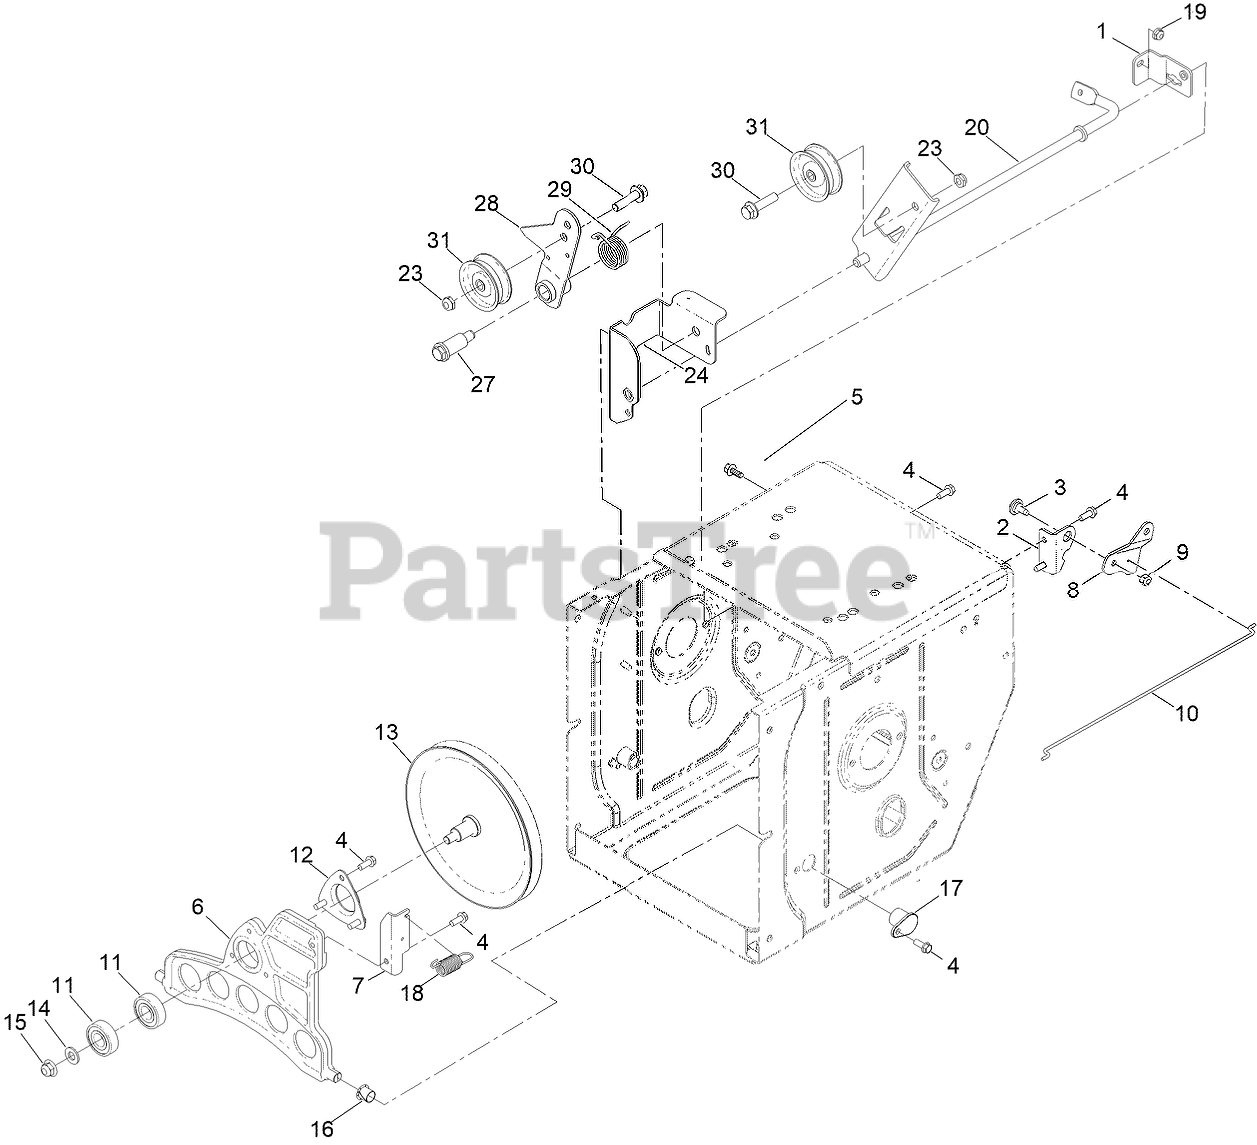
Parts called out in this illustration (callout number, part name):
1	BRACKET-CLUTCH, IMPELLER
2	BRACKET- BELLCRANK
3	SCREW-SHOULDER
4	SCREW-HWH
5	SCREW-HHF
6	PLATE-FRICTION, WHEEL
7	BKT-TRACTION PLATE
8	BELLCRANK-DRIVE
9	NUT-HEX
10	LINK-DRIVE
11	BEARING-BALL
12	RETAINER-BEARING
13	PULLEY-TRACTION
14	WASHER-FLAT
15	NUT-HF, NI
16	BUSHING-NYLINER
17	BUSHING-PLATE, TRACTION
18	SPRING-EXTENSION
19	NUT-HF
20	ARM-CLUTCH, IMPELLER
23	NUT-HEX
24	BRACKET-BRAKE, CLUTCH
27	BOLT-SHOULDER
28	ARM-IDLER, TRACTION
29	SPRING-TORSION
30	SCREW-HHF
31	PULLEY-IDLER
